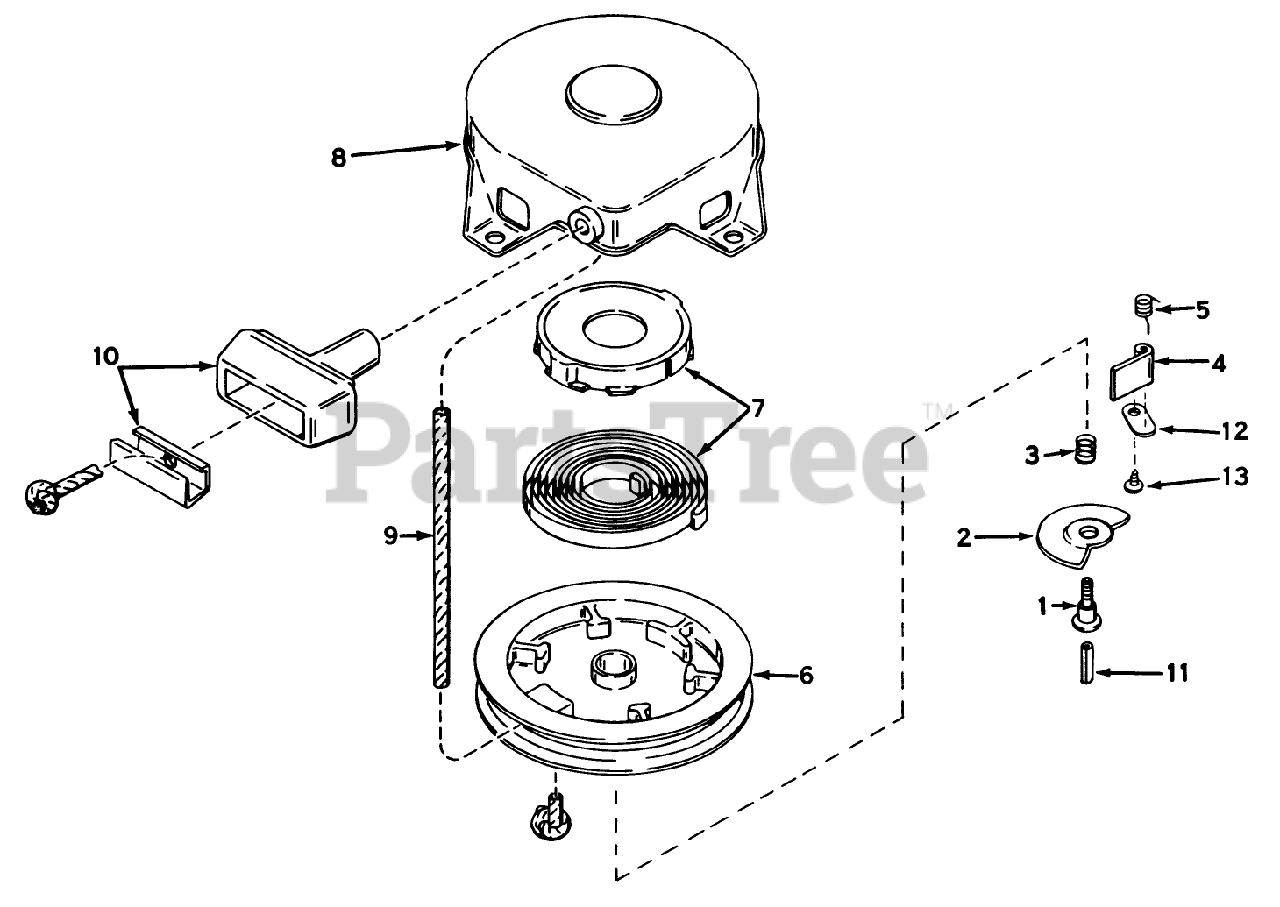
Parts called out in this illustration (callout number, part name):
2	Cam-Dog
3	Spring-Brake
4	Dog-Starter
5	Spring-Dog
7	Spring & Keeper Assy
8	Housing Assembly, Starter (Incl. #1)
9	Rope, Starter
10	Assy., Starter
11	Centering
12	Retainer-Dog
